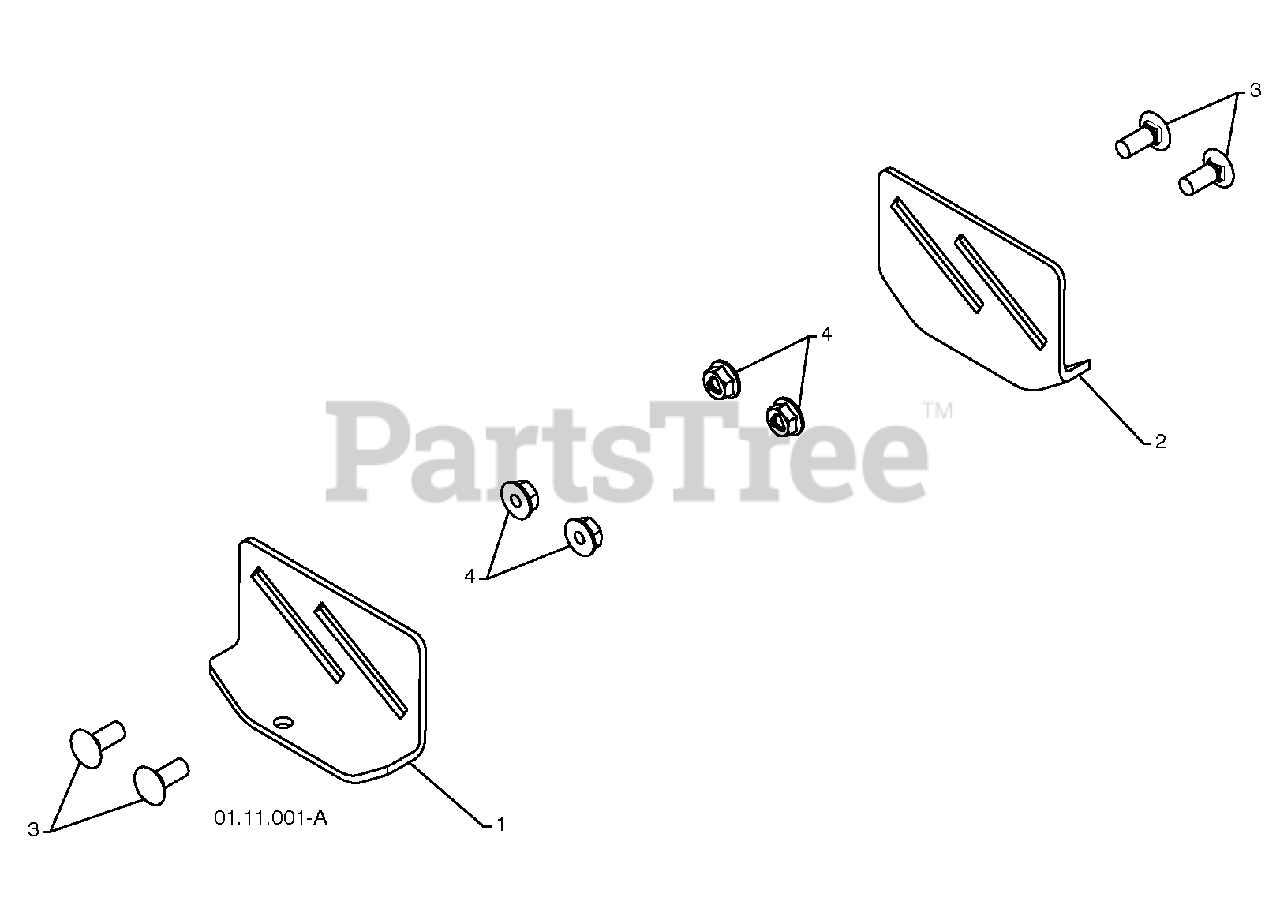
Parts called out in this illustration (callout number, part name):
1	SKID PLATE LH
2	SKID PLATE RH
3	CARRIAGE BOLT 5/16-18 X .75
4	NUT 5/16-18
